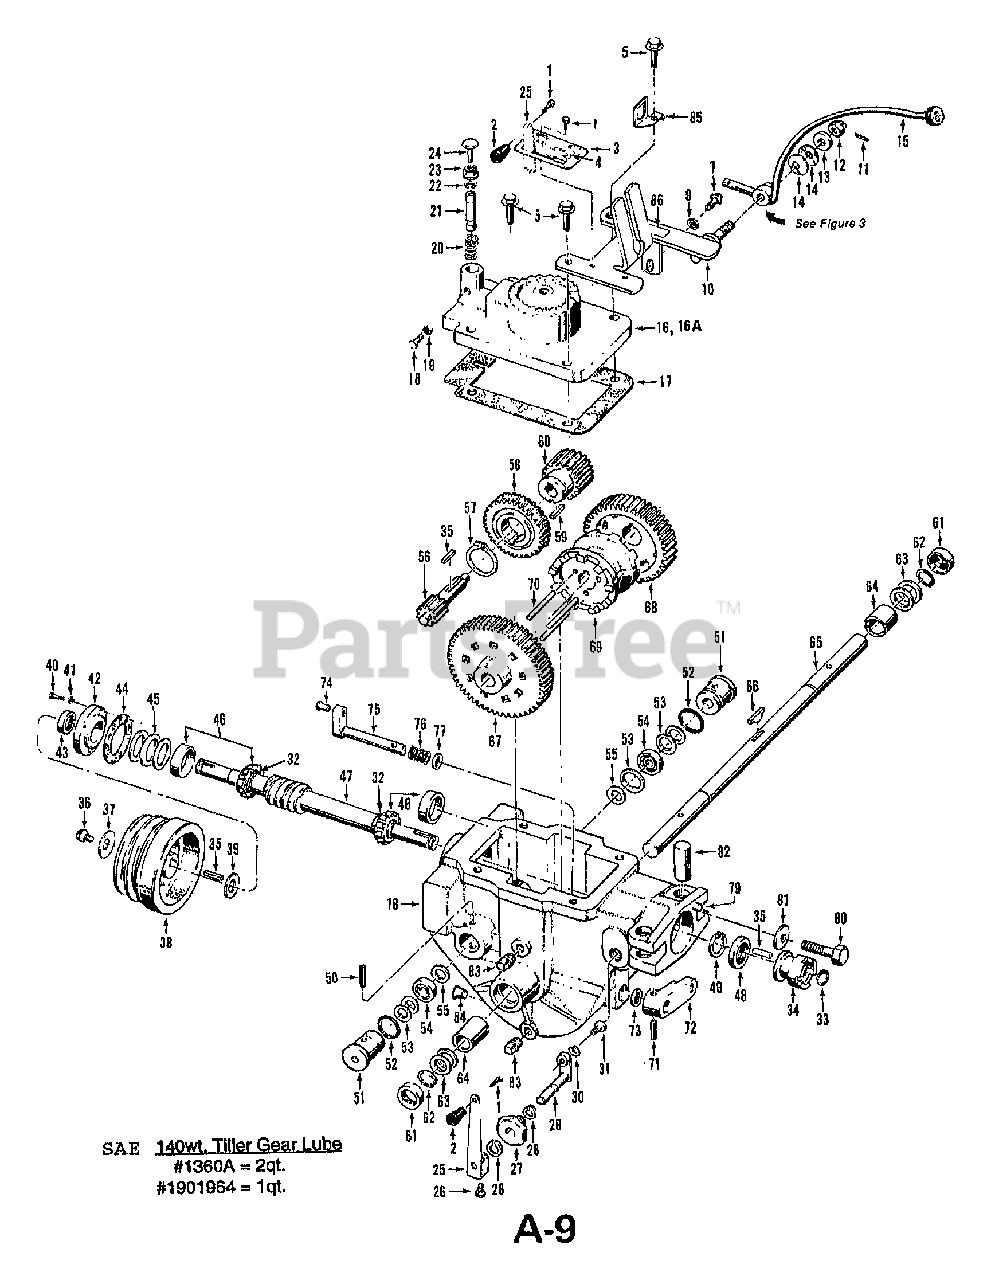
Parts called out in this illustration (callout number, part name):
1	SCR 10-32
2	KNOB-TAPERED
3	PLATE-TINE ENGAGE W/DECAL
4	DECAL-TINE ENGAGE
5	SCR-HFLK 3/8-16X1.50
7	SCR-HFLK 5/16-18X.75 ZP
9	WASHER-FLAT 5/16 SAE
10	BRKT-H HOOD 2149
11	PIN-SPRING .125 X 1
12	NUT
12	NUT-HEX 1/2-20 CALL TECH. SERVICE DEPT. FOR TIGHTENING INSTRUCTIONS.
13	WASHER-# SHOULDER ZP (SHOULDER FACES DISC WASHERS)
14	WASHER-# 1.97X1X.118 (CONCAVE SURFACES FACE EACH OTHER)
15	LEVER
16	COVER-TRANS RED 2523
16A	ASSM-TRANS COVER OPC
17	GASKET-TRANS COVER
18	SCR-HH 5/16-18X1.0 G5 ZP (REMOVE WITH CARE) SEE REF.#'S 20 & 21
19	NUT-HEX 5/16-18 ZP
20	SPRING-REV PLUNGER ZP (REMOVE WITH CARE)
21	ASSM-NEUTRAL PLUNGER (REMOVE WITH CARE) INCLUDES #9504 CLIP RING(REF.#22)
22	RING-KLIP EXT .594 ID ZP
23	NUT-HFLK 3/8-16 ZP
24	SCR 3/8-16X1.5 UNC-2AG
25	LEVER-ECCENTRIC RED (ALSO SEE REF.#'S 1,2 3 AND 4 LISTED ABOVE)
26	SCR-HH 1/4-20X.5 GR5 YEL
27	BUSHING-.87X.5X.62 ECC
28	RING-RETAINING 5100-50
29	SHAFT-WELD ECCENTRIC
30	WASHER-LK .25 HI-COLLAR
31	SCR-HXSKT 1/4-20X.38 G8
32	SHIM-1.0X.7656X.062 SHOULDER(DRIVE SHAFT)
33	RING-RETAIN EXT .707 ID
34	KIT-CLUTCH DOGS TILLER
35	KEY-.188 SQX1.0 (USED ON DRIVE SHAFT AND PINION SHAFT)
36	SCR-HH 5/16-24X.75 G5 ZP
37	WASHER-.827X.331X.098
38	PULLEY-TRANS MACH
39	WASHER-SHLDR HARDENED
40	SCR-HH 1/4-20X.75 G5 ZP
41	WASHER-LK .25 ZP
42	COVER-FRONT
43	SEAL-PINION SHAFT PT/85030/00
44	GASKET-BRG COVER
45	SHIM-1.75X1.5X.01
45	SHIM-1.75X1.5X.03
45	SHIM-1.75X1.5X.005
45	SHIM-1.75X1.5X.062
46	KIT-BRG CONE&RACE-DRIVESHAFT
47	KIT-WHEELDRIVE ROLL/WORM
48	SEAL-OIL DRIVESHAFT
49	RING-RETAINING 5000-181
50	PIN-SPIROL .25 X 2.0 (REF.#51)
51	PLUG-PINION BRG W/RING (REF.#52)
52	RING-O 1 ID
53	SHIM-1.234X1.015X.033
53	SHIM-1.234X1.015X.062
53	SHIM-1.234X1.015X.01
54	BRG-BALL (7 BALLS)
55	WASHER-# 1X.484X.06
56	GEAR-SPLINE 10 TEETH MACH (DRIVES SLOW SPEED WHEEL GEAR)
57	RING-RETAINING 5100-150
58	GEAR-WORM MACH
59	KEY
60	GEAR-SPUR 20 TEETH MACH (DRIVES FAST SPEED WHEEL GEAR)
61	SEAL-OIL WHEELSHAFT
62	RING-HEAVY EXT .906 ID
63	SHIM-1.375X1.015X.062
63	SHIM-1.375X1.015X.03
63	SHIM-1.375X1.015X.015
63	SHIM-1.375X1.015X.01
63	SHIM-1.375X1.015X.005
64	BUSHING-1.25X1.005X1.5
65	KIT-WHEELSHAFT
66	KEY-HI PRO .25X1.812
67	GEAR-SPUR 56 TEETH MACH
68	GEAR-SPUR 46 TEETH MACH
69	CLUTCH-MACH
70	PIN-CLUTCH .25 2.65
71	PIN-SPIROL .188 X 1.25
72	LEVER-ECC. #1029
73	SEAL-OIL ECCENTRIC
74	PIN-.375 X .72
75	SHAFT-ECCENTRIC HORSE TLR
76	SPRING .845 X 1.25
77	WASHER # .875 X .65 X .06
78	CASE-TRANS W/PIN
79	PIN-DRIVE .375X.75 ZP
80	SCR-HH 1/2-13X2.0 G5 ZP
81	WASHER-DISC SPRING
82	POST (TC) WITH THREADED HOLE FOR #9560 BOLT( REF.#80)
83	PLUG-PIPE 1/4 NPT
84	PLUG-CAP (RED)
85	CLIP-CONNECTOR (ALSO SEE PAGE 16)
86	DECAL-FWD INTERLOCK WIRE
